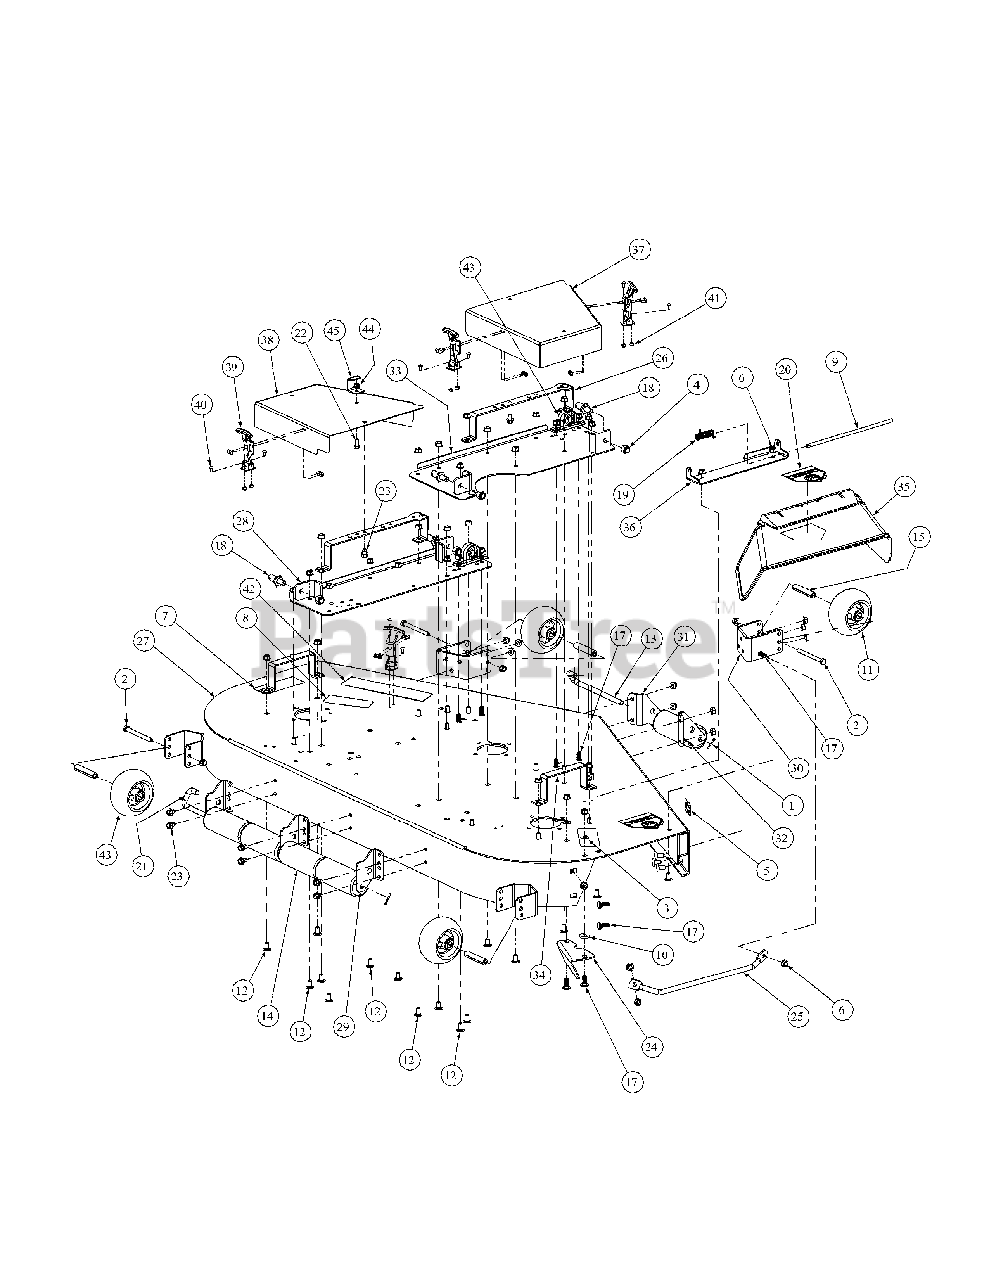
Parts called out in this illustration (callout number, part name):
1	Cotter Pin, .125 Dia. x 1.0
2	Hex Cap Screw, 3/8-16, 3.75
3	Flat Washer, 3/8
4	Lock Nut, Nylon Insert, 1/2-13
5	Label, 60"
6	Flange Lock Hex Nut, 3/8-16
7	Decal, Rotating Blade
8	Decal, Warning Shield Missing
9	Chute Deflector Rod
10	Idler Washer
11	Complete Wheel, 5.00 Dia.
12	Carriage Bolt, 3/8-16 x .75 Lg.
13	Roller Pin, 1/2 Dia. x 7.31 Lg.
14	Front Roller
15	Wheel Spacer
17	Carriage Bolt, 3/8-16 x 1
18	Pin, 5/8 Dia. x 1.2 Lg.
19	Torsion Spring, 0.4ID x 2.16Lg
20	Decal, Danger Hand and Feet
21	Roller Pin
22	Hex Cap Screw, 5/16-18 x .75
23	Hex Index Washer Screw, 3/8-16, .5
24	Chute Bracket
25	Finger Guard
26	Belt Cover Support
27	60 Deck Assembly
28	Left Hand Mount Deck Bracket Assembly
29	Deck Roller Mount Bracket
30	Anti-Scalp Wheel Front Mount Bracket
33	Right Hand Deck Bracket Assembly
34	Outer Belt Cover Support Assembly
35	Chute Deflector
36	Chute Deflector Bracket
37	Right Hand Deck Belt Cover Weldment
38	Left Hand Deck Belt Cover Weldment
39	T-Handle Latch Draw
40	Phillips Head Screw, 10-32
41	Lock Nut, Nylon Insert, 10-32
42	Commercial Mower Label
43	Pillow Block
44	Nut, 5/16-18, Hex Flange Lock
45	Stop Bracket
